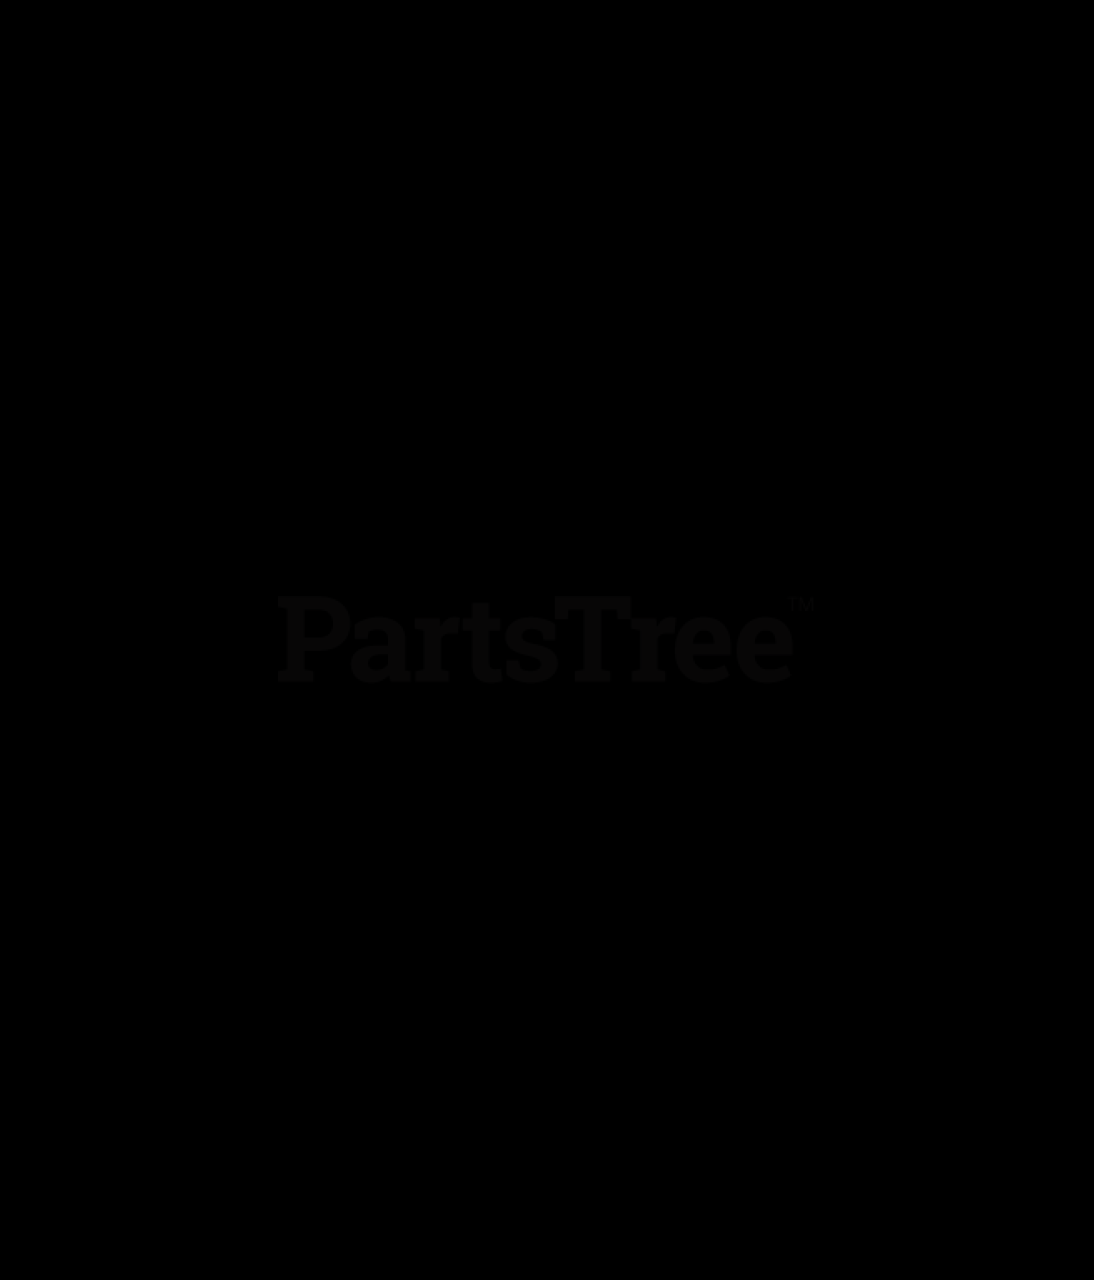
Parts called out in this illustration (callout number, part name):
1	Engine, 27HP Daihatsu Diesel (950D) (582447-0405-E2) (992215, 218)
2	Muffler (992215)
3	Sender, Temperature
4	Bolt, Hex .31-18 x .75 Grade 5
5	Nut, Locking Top Flange .31-18
6	Gas Line, Bulk .31" ID
7	Hose, Clamp
8	Mount, Engine Right Hand
9	Mount, Engine Left Hand
10	Washer, Lock .31 x .078 Regular
11	Bolt, Hex M8-1.25 x 20
12	Bolt, Hex M8 x 1.25 x 25 Grade 8
13	Bracket, Air Cleaner
14	Clamp, Hose #32 (1.56" – 2.50")
15	Assembly, Air Cleaner
16	Mount, Engine
17	Bolt, Hex .50-20 x 1.00 Grade 5
18	Washer, Locking .50 x .125 Regular
19	Clamp, Hose 1.50 x .81 x 1.42
20	Hose, Air Cleaner (992215, 218)
21	Washer, Flat Steel .38 x .875 x .083
22	Nut, Locking, Top M8-1.25
23	Bracket, Air Cleaner Mount
24	Washer, Flat Steel .38 x .875 x .083
25	Spacer, Engine Mounting
26	Washer, Flat Steel .531 x 1.06 x .095
27	Reducer, Hose, Elbow .31ID/ .25ID
28	Oil Filter
29	Element, Inner Safety
30	Element, Outer Primary
31	Plug, Pipe .125-27
32	Bolt, Hex M6-1 x 16
33	Hose, .25 Low, Perm, Bulk Gas
34	Clamp, Fuel Line
